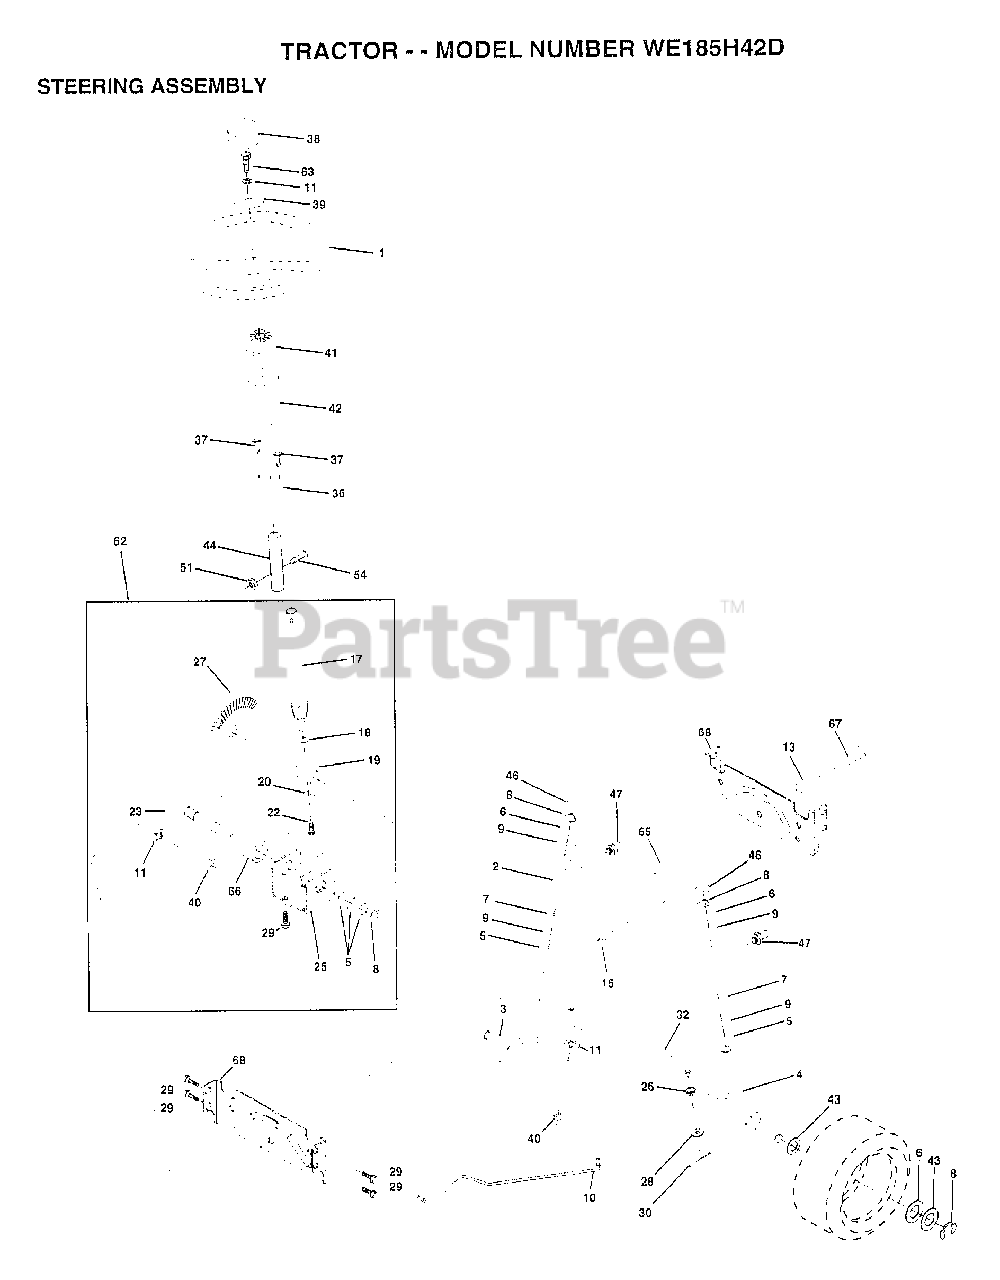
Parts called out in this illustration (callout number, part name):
1	WHEEL STR AYP BLK
2	AXLE ASM
3	SPINDLE.ASM.LH
4	"SPINDLE ASM,RH"
5	WASHER .T
6	WASHER
7	WASHER
8	RING
9	COL. SRTG. BEAR.
10	DRAGLINK-STAMPED
11	LOCKWASHER
13	BEARING AXLE
15	"NUT-LOC,FLANGE LT"
17	SHAFT ASM STEERIN
18	THRUST WASHER
19	SUPPORT.SHAFT
22	SCREW HEX SOC1/4-
25	BRKT-STEERING
26	BUSHING.DRAGLINK
27	GEAR SECTOR
28	WASHER
29	SCREW
30	COTTER PIN
32	TIE ROD
36	BUSHING.STEERING
37	"SCREW-TT,10-32 FL"
38	CAP STEER AYP
39	WASHER T
40	GRIPCO NUT
41	ADAPTER LT
42	BOOT.STEER.PL
43	WASHER
44	EXT SHAFT STEERIN
46	CAP
47	ZERK M
51	NUT
54	BOLT
62	KIT STEERING ASM
63	BOLT
65	SPACER AXLE
66	"BEARING-ARM,PITMA"
67	BOLT
68	BRACE AXLE
